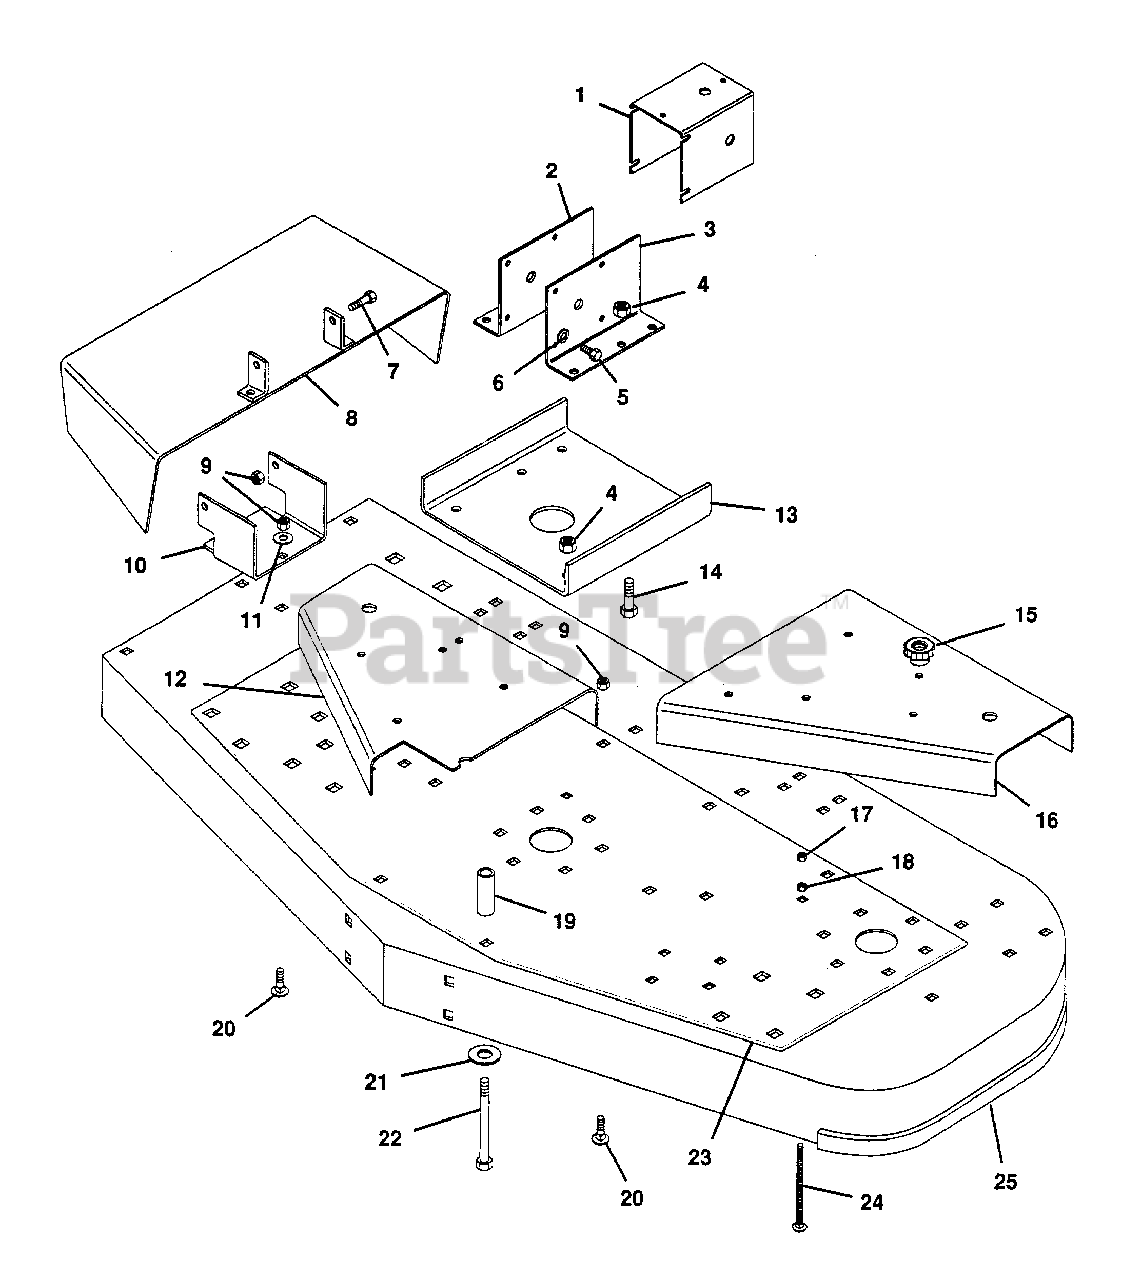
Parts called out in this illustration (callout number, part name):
1	Shield, U-Joint
2	Bracket, Gearbox Mounting R.H.
3	Bracket, Gearbox Mounting L.H.
4	Nut, Lock 1/2-13
5	Bolt, Hex 3/8-16x.875
6	Washer, Lock 3/8 Reg.
7	Bolt, Hex 3/8-16x1.00
8	Weldment, Discharge Chute
9	Nut, Lock 3/8-16
10	Bracket, Discharge
11	Washer, Flat .406x.812x.065
12	Cover, Belt R.H.
13	Plate, Support
14	Bolt, Hex 1/2-13x1.00
15	Knob
16	Silkscreen, Belt Cover
17	Nut, Lock 5/16-18
18	Nut, Jam 5/16-18 Hex
19	Bush., St. .562x1.00x2.00 Stl.
20	Bolt, 3/8-16x1.00 Rd Hd Sq Nk
21	Washer, Flat .531x1.062x.095
22	Bolt, Hex 1/2-13x3.75
23	Plate, Deck Support
24	Bolt, 5/16-16x4.0 Rd Hd Sq Nk
25	Weldment, 72" Deck
